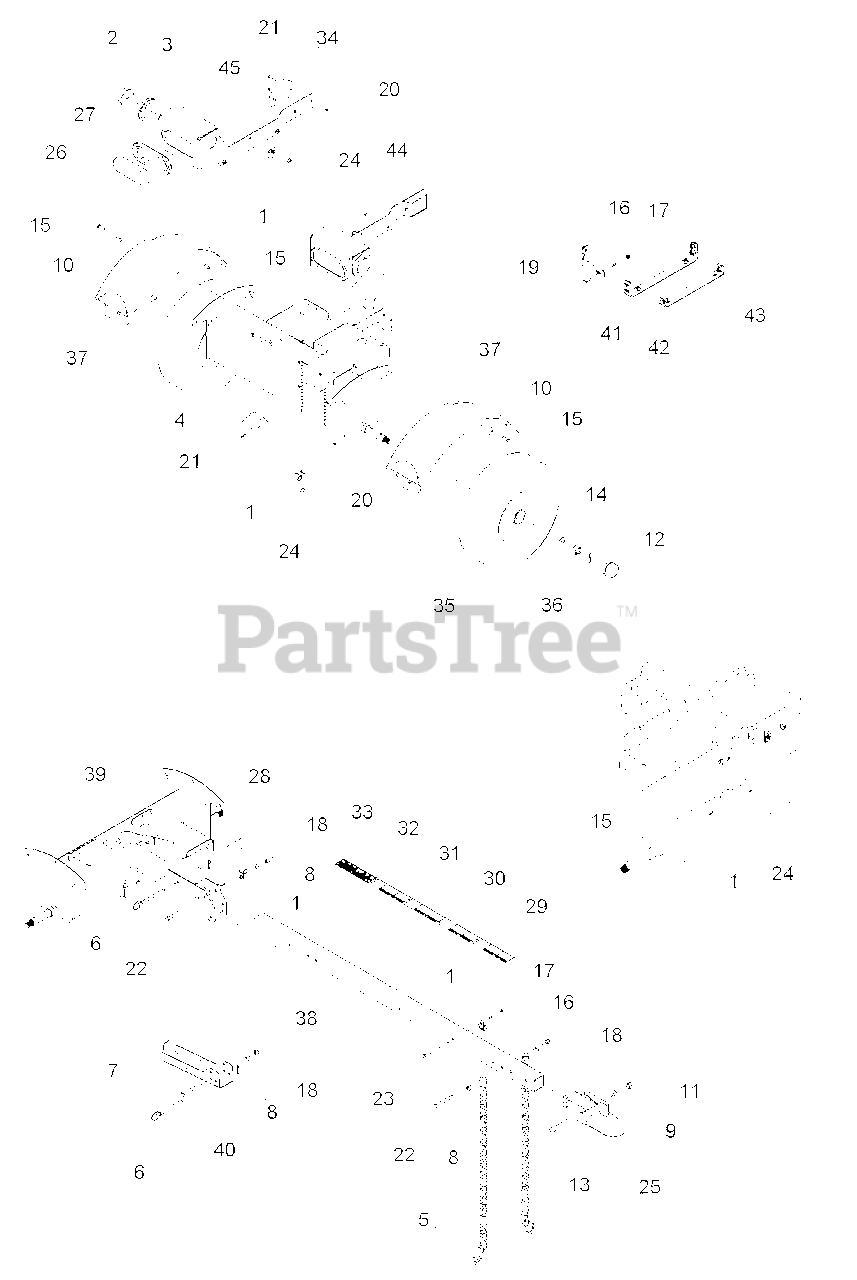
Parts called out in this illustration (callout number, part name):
1	CLAMP, 9/16 COATED
2	LIGHT, RED CLEARANCE
3	GROMMET, CLEARANCE LIGHT
4	LIGHT, LICENSE PLATE
5	CHAIN, SAFETY 5000 LB W/ LATCH
6	PIN, 3/8 HITCH
7	BOLT, 3/8 X 3-1/2 HEX HD GR5 ZP
8	WASHER, 3/8 FLAT ZP
9	WASHER, 1/2 FLAT ZP
10	WASHER, 5/16 FENDER ZP
11	NUT, 1/2 CENTERLOCK GRB ZP
12	PIN, 5/32 X 1-1/4 COTTER ZP
13	BOLT, 1/2 X 3 HEX HD GR5 ZP
14	WASHER, 3/4 SAE FLAT ZP
15	BOLT, 5/16 X 1 HEX HD GR5 NC ZP
16	WASHER, 5/16 FLAT ZP
17	NUT, 5/16 NE NYLOCK ZP
18	NUT, 3/8 NE NYLOCK ZP
19	BOLT, 5/16 X 7/8 HEX NC GR5 ZP
20	NUT, 10/24 NYLOCK TYPE NM ZP
21	MACH. SCREW, #10-24 X 3/4 PAN HD PH ZP
22	BOLT, 3/8 X 3-1/4 HEX HD GR5 ZP
23	BOLT, 5/16 X 2-3/4 HEX HD GR5
24	NUT, 5/16 FLANGE TOPLOCK
25	TRAILER HITCH COUPLER
26	TAIL LIGHT, OVAL LED
27	GROMMET, OVAL TAIL LIGHT
28	DECAL, 4.80-8 LOAD RATING (LOG SPLITTER)
29	DECAL, SAFETY CHAINS
30	DECAL, TRAILER ELECTRICAL
31	DECAL, PINTLE SAFE COUPLING
32	DECAL, CHECK WHEELS
33	DECAL, SAFE TOWING SPEED
34	LIGHT, AMBER SIDE MARKER
35	ASSEMBLY, TIRE 4.8-8
36	NUT, SLOTTED 3/4-16 GRADE 2
37	FENDER, BLACK PLASTIC DRILLED
38	TUBING, HITCH POLE
39	WELDMENT, SC 3" TRAILER
40	STAND, JACK
41	BRACKET, CORNER
42	BRACKET, ENGINE BASE
43	BRACKET, ENGINE BASE
44	BRACKET, RIGHT TAIL LIGHT
45	BRACKET, LEFT TAIL LIGHT
